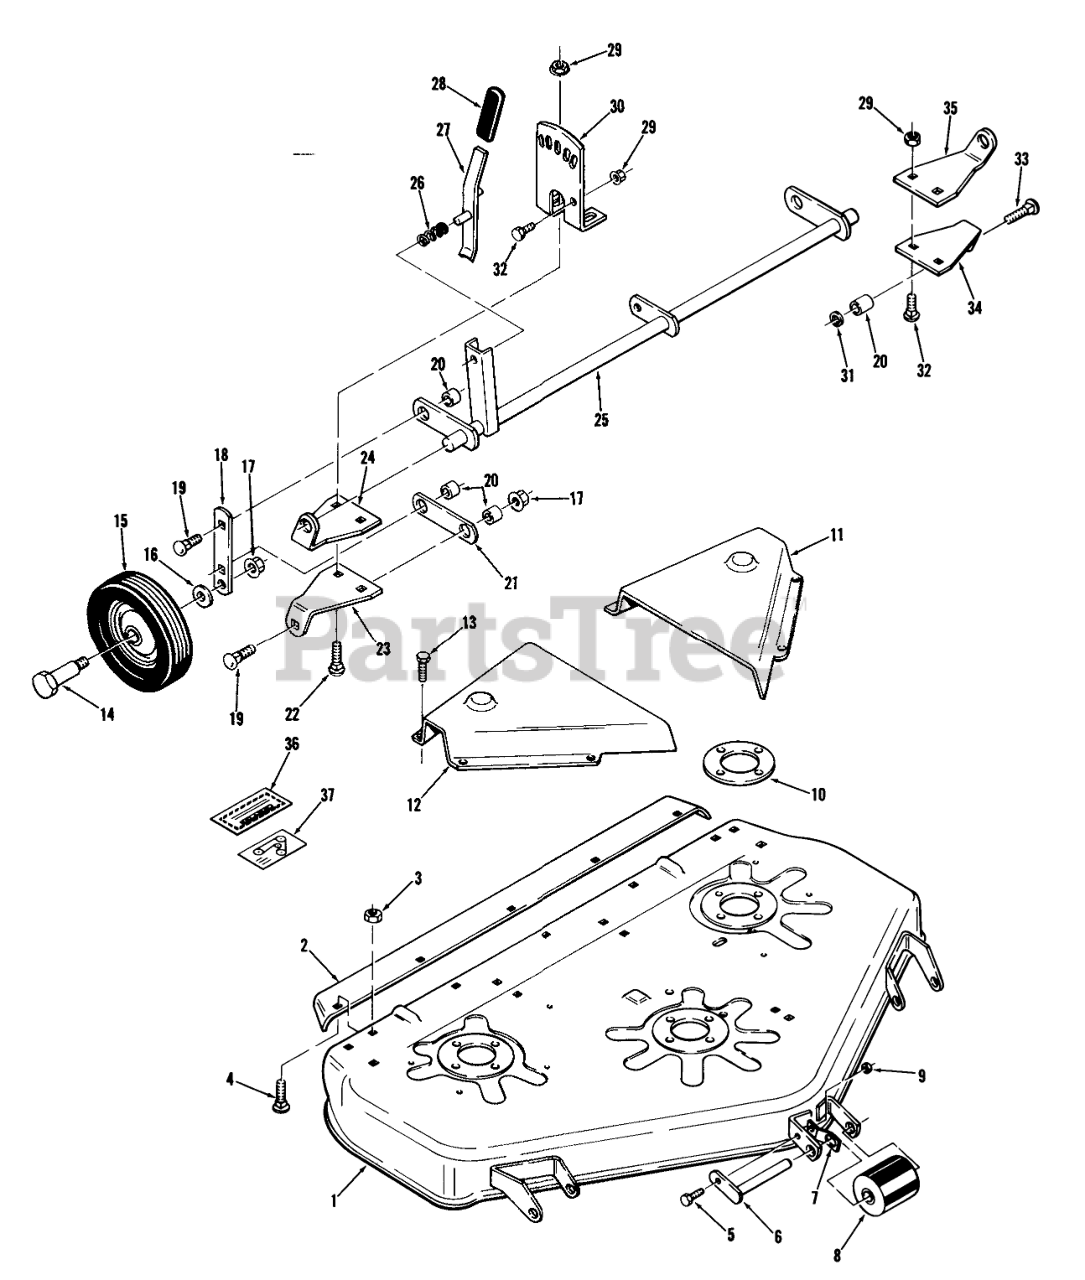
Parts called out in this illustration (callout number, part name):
1	Mower Deck Assembly
2	Grooved Pin 5X28MM
3	Nut
4	CARRIAGE BOLT -4
5	H H C S
6	Roller Shaft
7	SPRING ROLLER STOP
8	Roller
9	Nut
10	PLATE-SPINDLE
11	L.H. Belt Cover
12	R.H. Belt Cover
13	Bolt
14	BOLT-SHOULDER
15	Wheel
16	WASHER
17	LOCKNUT-FLANGE
18	WHEEL SUPPORT LINK
19	Bolt
20	SPACER
21	SUPPORT LINK R
22	Bolt
23	Bracket-Lower R.H.
24	Bracket-R.H. Upper
25	Gage Wheel Support
26	SPRING-COMPRESSION
27	Lever
29	LOCKNUT-FLANGE
30	Quadrant
31	WASHER
32	Bolt
33	Bolt
34	Bracket-L.H. Lower
35	Bracket-L.H. Upper
36	Caution Decal
37	Decal Belt Diagram
